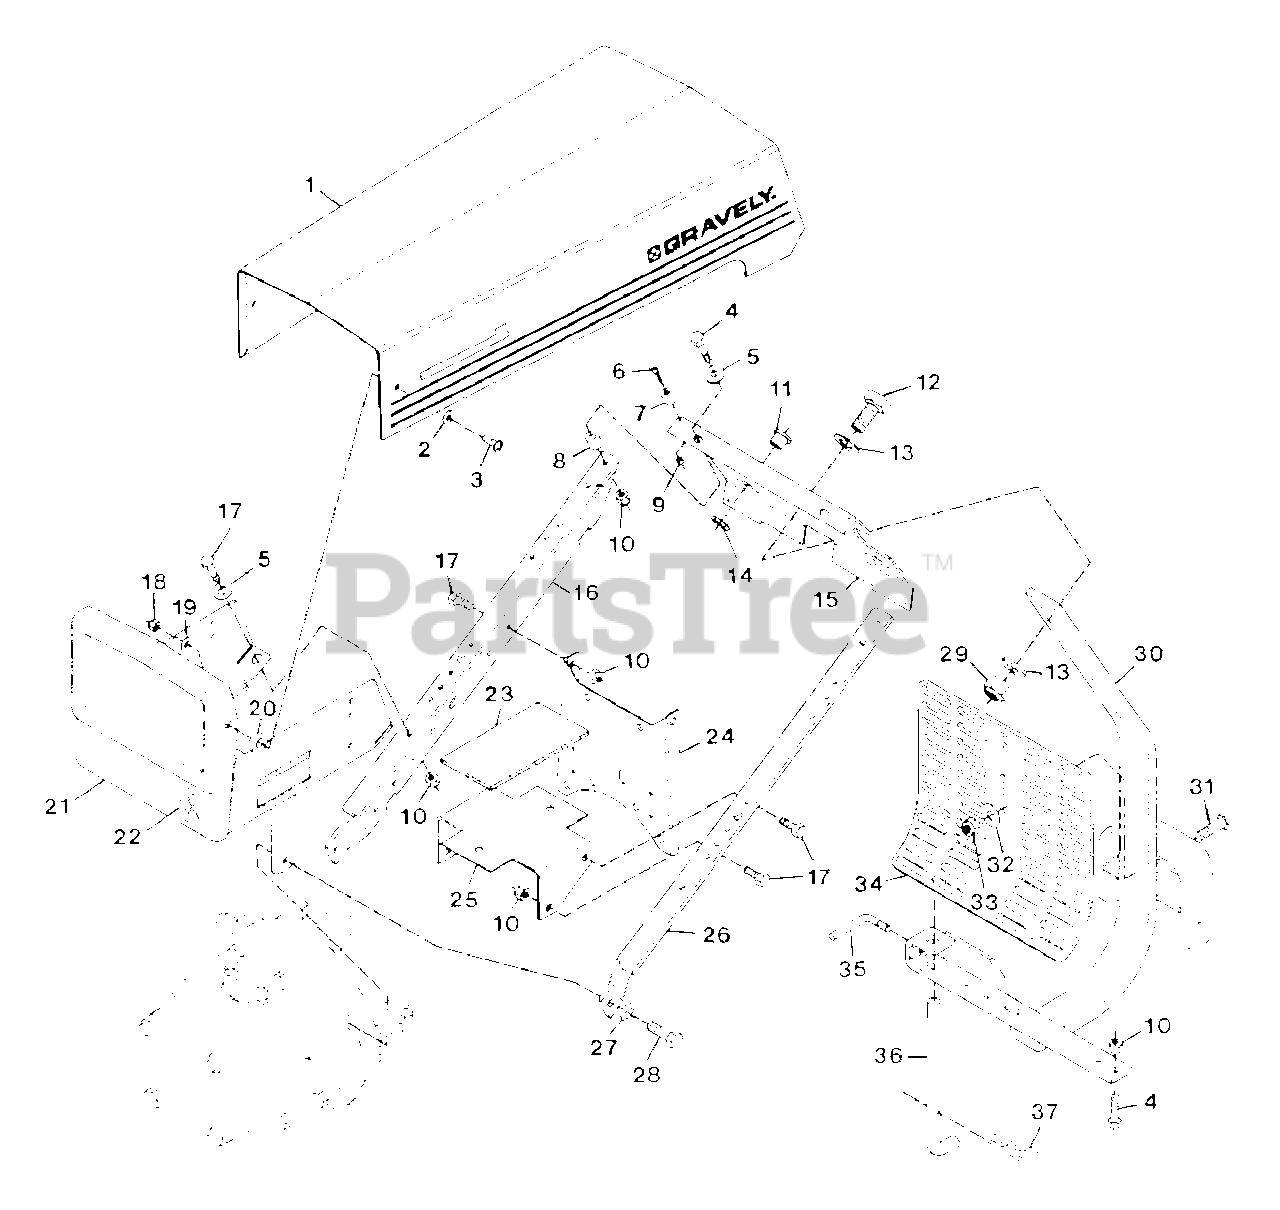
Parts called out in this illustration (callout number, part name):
1	Assembly, Hood
2	Washer, Flat .281x.625x.065
3	Screw, Mach. 1/4-20x1.00 PHD
4	Bolt, Hex 3/8-16x1.50
5	Washer, Flat .406x.812x.065
6	Screw, Mach. 6-32x.625 PHD
7	Bumper
8	Bushing, Reverse Idler
9	Nut, Mach. Lock 6-32
10	Nut, Lock 3/8-16
11	Bushing, .513x.750x.625
12	Bolt, Hex 5/8-11x2.00
13	Washer, Flat .656x1.250x.100
14	Ring, Retaining
15	Plate, Silk Screen (Manual)
15	Plate, Silk Screen (Electric)
15	Plate, Silk Screen (12 HP QS)
16	Support, Handlebar R.H.
17	Bolt, Hex 3/8-16x.875
18	Nut, Lock 1/4-20
19	Washer, Flat .313x.875x.065
20	Bushing, Hood
21	Weldment, Battery Bracket
22	Decal
23	Pad, Gas Tank
24	Bracket
25	Bracket, Tank Support
26	Support, Handlebar L.H.
27	Washer, Lock 1/2 Reg.
28	Bolt, Hex 1/2-13x1.00
29	Nut, Lock 5/8-11
30	Weldment, Hitch 10 and 12 H.P.
31	Bolt, Hex 1/2-13x1.50
32	Washer, Flat .531x1.250x.100
33	Nut, Lock 1/2-13
34	Guard, Engine
35	Handle, Adjusting
36	Stand, Kick
37	Pin, Hair
NS	Decal, 10
NS	Decal, 12
NS	Decal, 16
NS	Decal, Side Stripe
NS	Decal, Gravely Logo
NS	Decal, 6 Lead
NS	Decal, 8 Lead
NS	Decal, Professional
